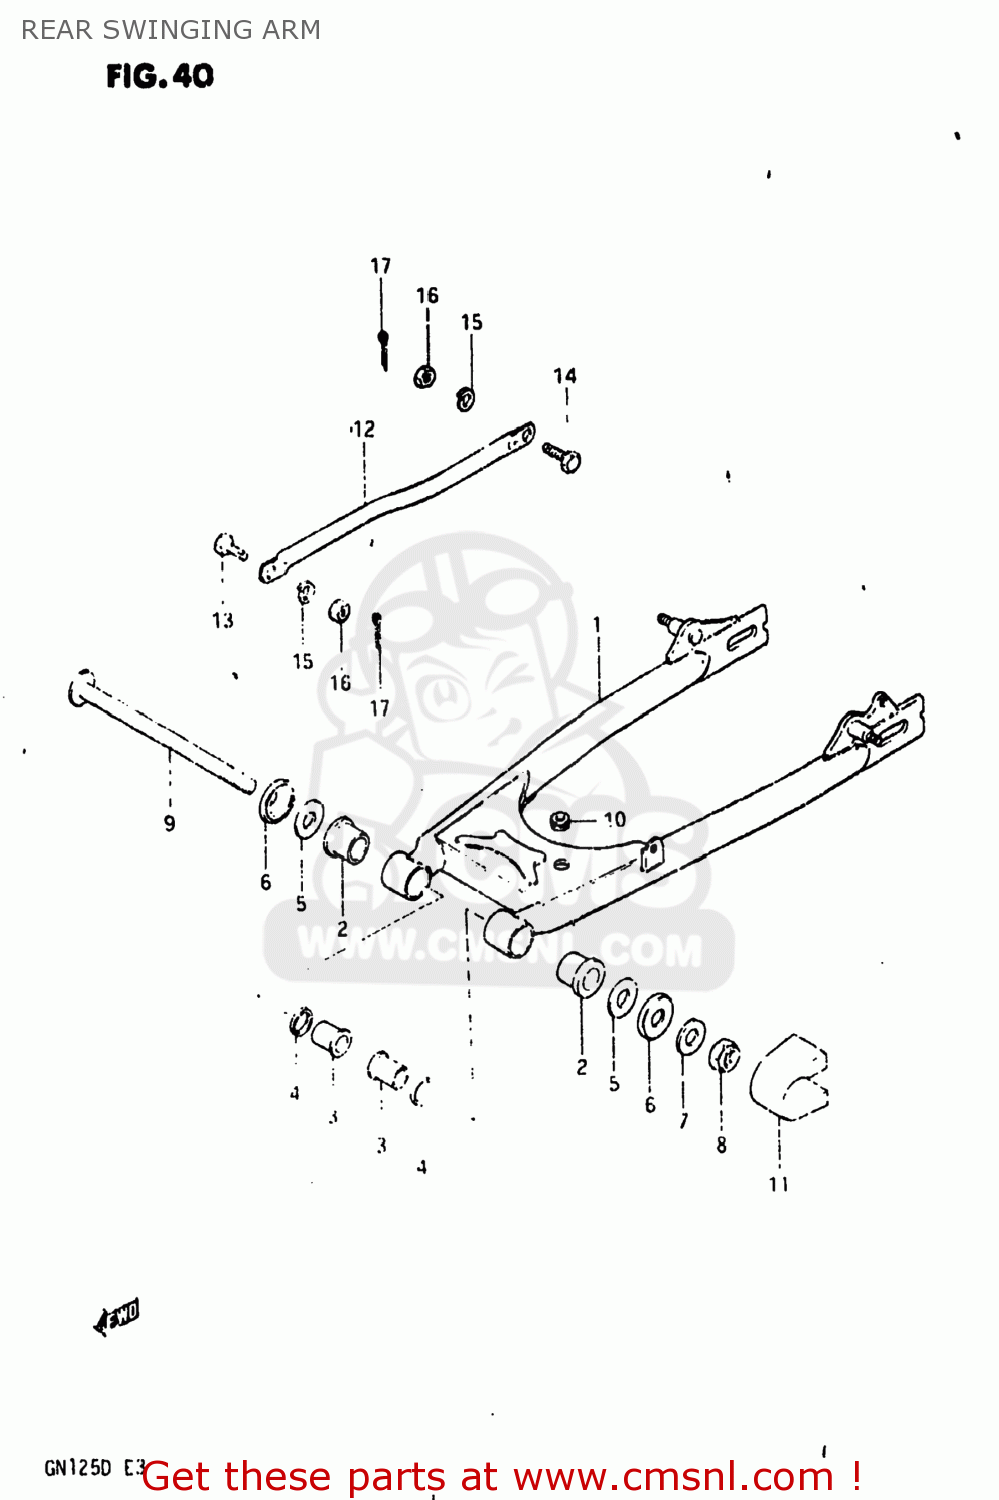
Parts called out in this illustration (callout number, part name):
1	SWINGINGARM ASSY,RR
2	BUSHING,REAR SWING ARM PIVOT
3	SPACER,RR SWGARM PIVOT
4	SEAL,OIL(20X27X5)
5	WASHER
6	CVR,RR SWGARM DUST SEAL(OD:40)
7	WASHER
8	NUT 14MM
9	SHAFT,REAR SWING ARM
10	CUSHION
11	BUFFER,CHAIN TOUCH DEFENSE
12	LINK,RR TORQUE
13	BOLT(8X22.5)
14	BOLT(8X26.5)
15	LOCK WASHER
16	NUT
17	PIN 20X20
